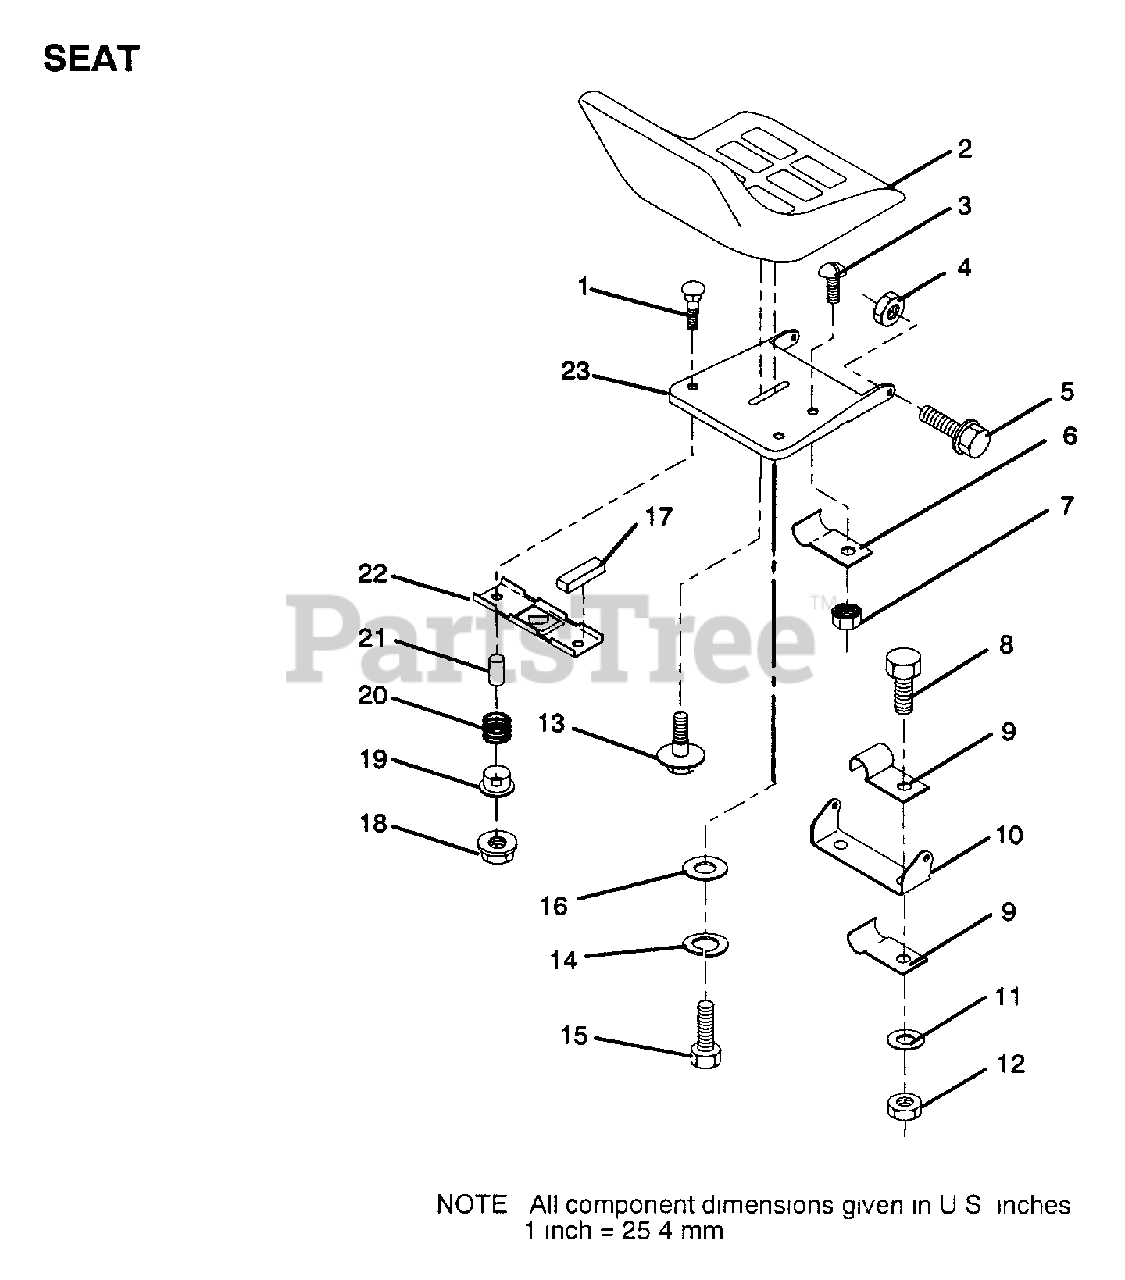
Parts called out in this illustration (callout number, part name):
1	BOLT
7	"NUT,KEPS"
9	"CLIP,INSULATOR"
11	WASHER
13	"BOLT,SHOULDER"
14	LOCKWASHER
15	BOLT
16	WASHER
17	STRIP FORM
19	BUSHING
20	SPRING
21	SPACER SPLIT
22	BRKT SWITCH
